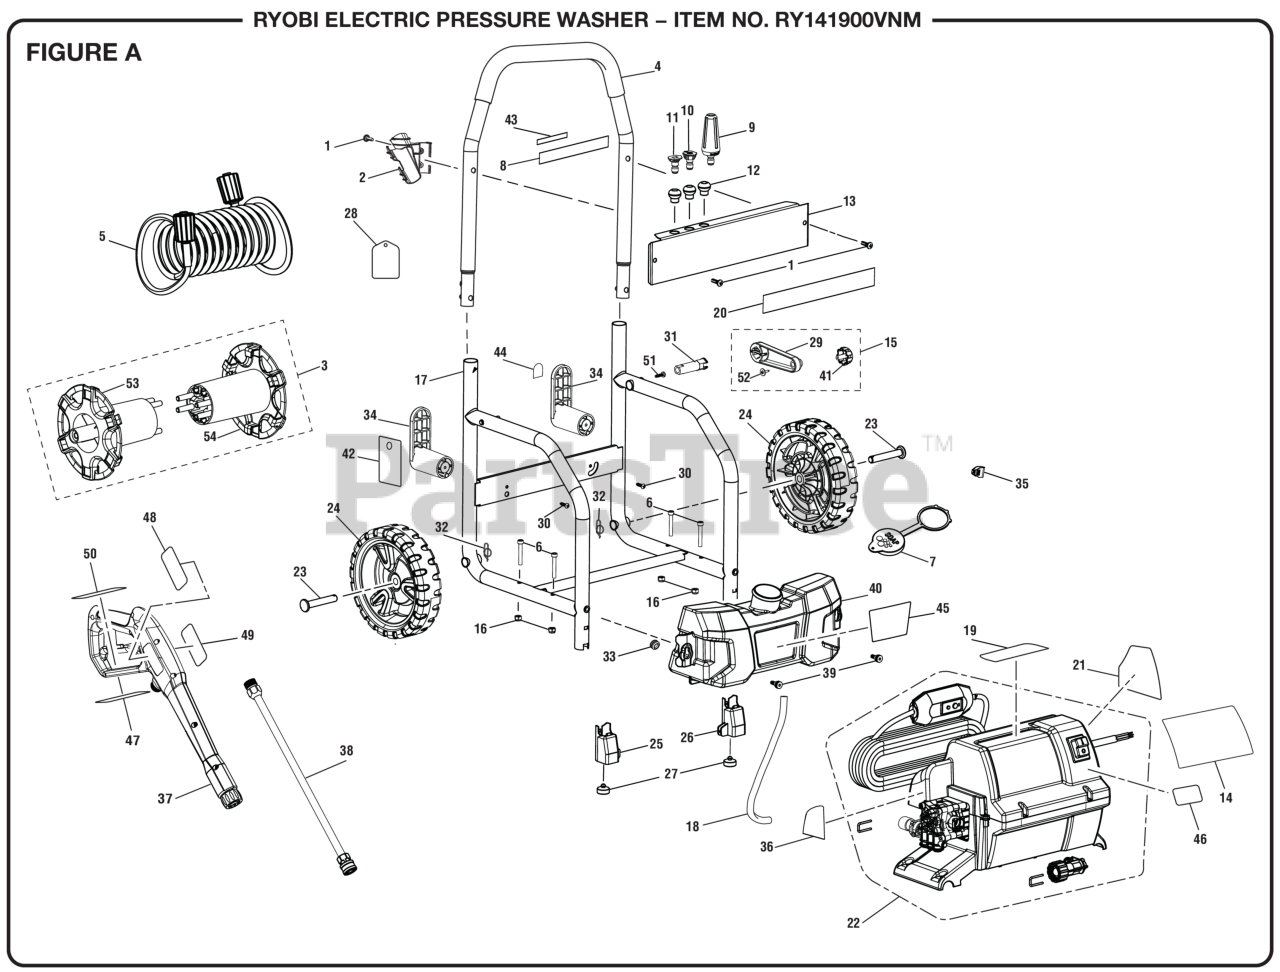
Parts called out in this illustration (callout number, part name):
1	Bolt (M6 x 20 mm, Philips Pan Hd.)
2	Trigger Handle Holder
3	Hose Reel Assembly
4	Handle Assembly
5	Hose (25 ft.) [PS141913]
6	Bolt (M6 x 40 mm, Socket Hex Hd.)
7	Detergent Tank Cap
8	Quick Start Label
9	Turbo Nozzle
10	Soap Nozzle (Blue)
11	Nozzle (15deg)
12	Nozzle Grommet
13	Performance Panel
14	Ryobi Logo Label
15	Hose Reel Handle Assembly
16	Lock Nut (M6)
17	Main Frame
18	Injection Hose
19	Nozzle Selection Label
20	Performance Label
21	Danger Label
22	Motor and Pump Assembly
23	Wheel Axle
25	Foot (Left)
26	Foot (Right)
28	Nozzle Hangtag (PS141913)
29	Hose Reel Handle Beam
30	Screw (M4.8 x 19 mm, Phillips Hd. S.T.)
31	Connection Shaft.
32	Hitch Pin
33	Soap Tank Grommet
34	Cord Wrap Arm
35	Electric Cord Clip
36	Pump Label
37	Trigger Handle
38	Spray Wand Assembly
39	Shoulder Bolt (M6 x 16 mm)
40	Detergent Tank
41	Hose Reel Handle Sleeve
42	Warning/Notice Hangtag
43	Inquires Label (Ryobi)
44	Power Cord Unlock Label
45	Detergent Tank Label
46	On/Off Switch Label
47	Trigger Handle Data Label
48	Trigger Handle Label (Logo Label)
49	Trigger Handle Warning Label (English)
50	Trigger Handle Warning Label (French/Spanish)
51	Screw (M4.2 x 15 mm, Phillips Hd. S.T.)
53	Left Reel
54	Right Reel
55	Screw (M3)
